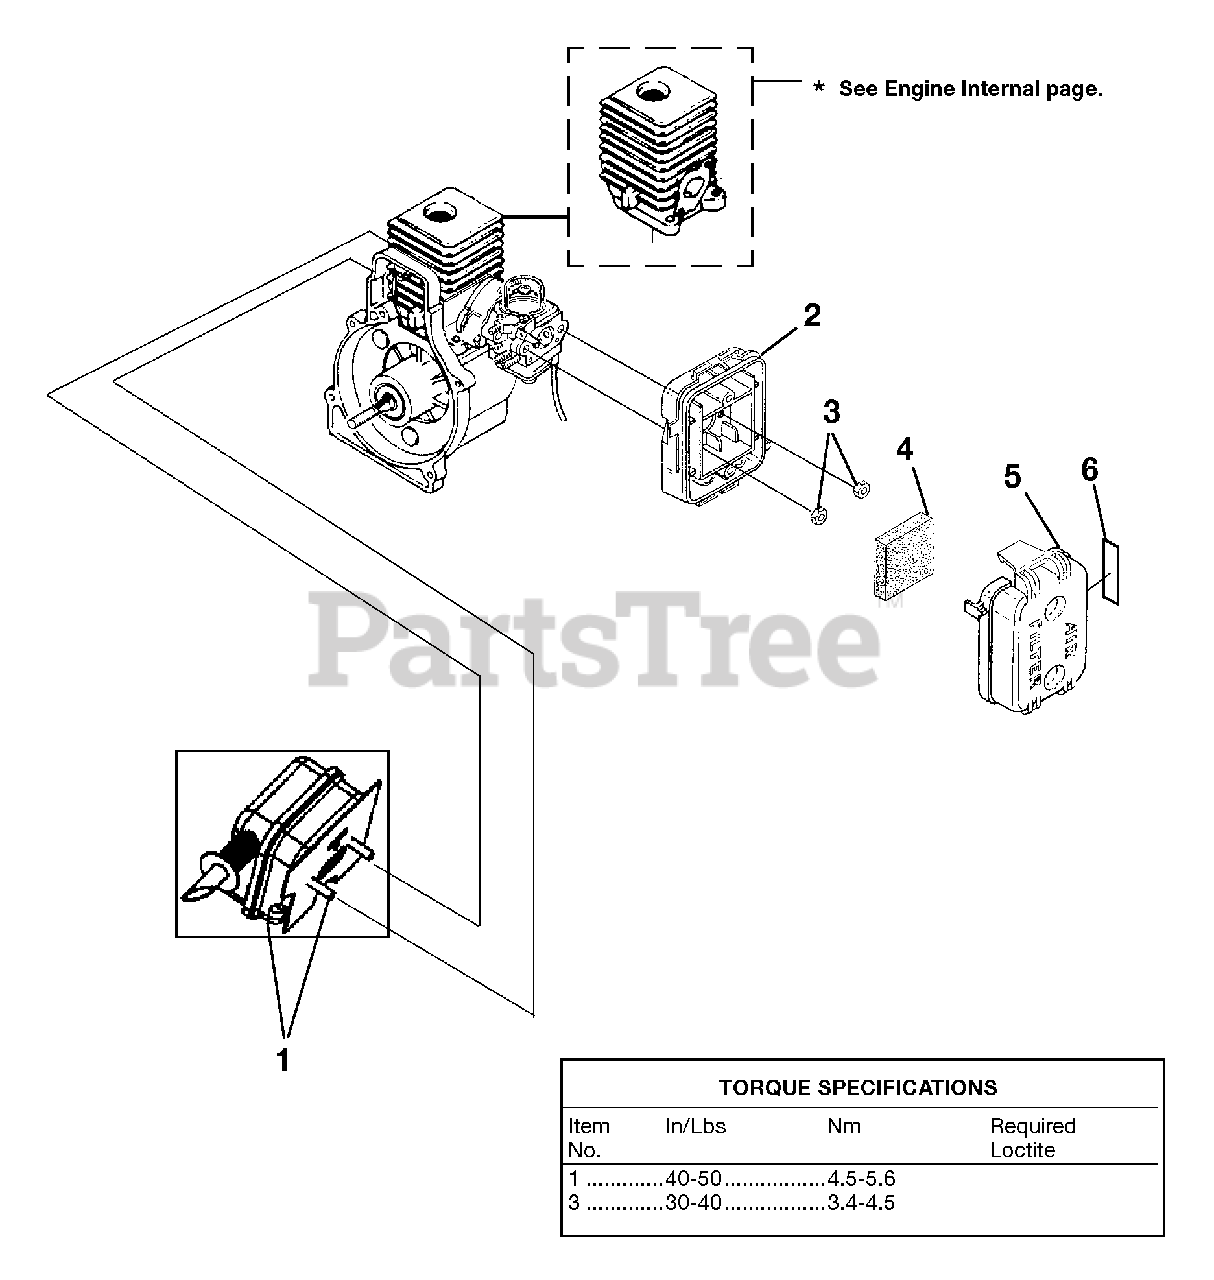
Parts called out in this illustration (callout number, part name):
1	MUFFLER-Complete
2	AIR FILTER BOX
3	NUT-Hex (10-24)
4	AIR FILTER
5	AIR FILTER COVER
6	DECAL-Choke
